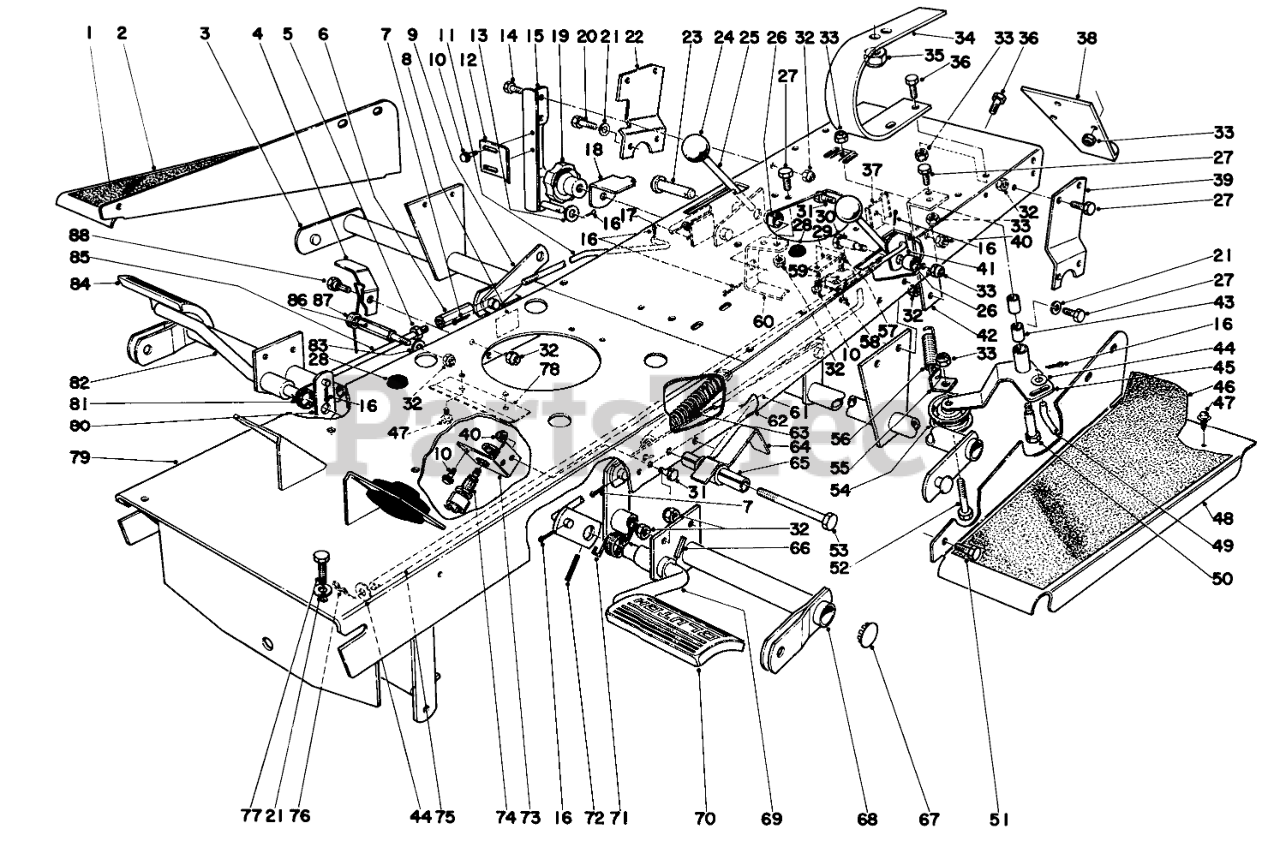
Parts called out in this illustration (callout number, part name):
1	Pad R. H.
2	Footrest R.H.
3	Cross Tube
4	Latch
5	NUT-JAM
6	Screw Brake Adjusting
7	PIN-COTTER
8	Decal Brake
9	Lift Link
10	SCREW-HH
11	Brake Rod Rear
12	Ball Joint
13	WASHER-FLAT
14	SCREW-HH
15	Brake Hanger
16	PIN-COTTER
17	Knob Plate
18	Slide
20	SCREW-HH
21	WASHER-LOCK
22	Support R.H.
23	Clevis Pin
24	Knob
25	Lever
26	Spacer
27	SCREW-HH
28	GROMMET
29	Bracket Switch
30	Shoulder Bolt
31	SCREW-HH
32	NUT-LOCK, CONE
33	NUT-LOCK, CONE
34	Seat Spring
35	1/2-13 CONELOCK NUT
36	SCREW-HH
37	Belt Guide
38	Hitch
39	Support Left
40	NUT-LOCK, CONE
41	Lever
42	Support Transaxle
43	BUSHING
44	WASHER-FLAT
45	Idler Arm (Incl. Ref. #43)
46	Pad Left
47	10-16 X 3/8 THDG SCREW
48	Footrest
49	Clutch Rod
50	Axle Bolt
51	SCREW-HH
52	SCREW-HH
53	SCREW-HH
54	PULLEY-IDLER
56	Tension Spring
57	SCREW-HEAD, PAN
58	NUT-LOCK, NI
59	MICRO SWITCH
60	Support Guide
61	Lift Equalizer
62	Retainer Clutch Lock
63	Spring Counterbalance
64	Clutch Lock
65	Spacer
66	PIN-SPRING
67	Plug Button
68	Cross Tube Front
69	Pedal Left
70	CLUTCH PAD
71	Pedal Return Spring
72	PIN-ROLL
73	Mounting Bracket Switch
74	Neutral Switch
75	Rod Clutch
76	PIN-COTTER
77	He Ha. Screw
78	Clamp-Wire
79	Frame
80	Lever Pedal Shaft
81	Pedal Return Spring
82	Pedal R.H.
83	Washer
84	PAD-BRAKE
85	Brake Rod Front
86	Brake Stop
87	Spring-Brake Latch
88	Screw
